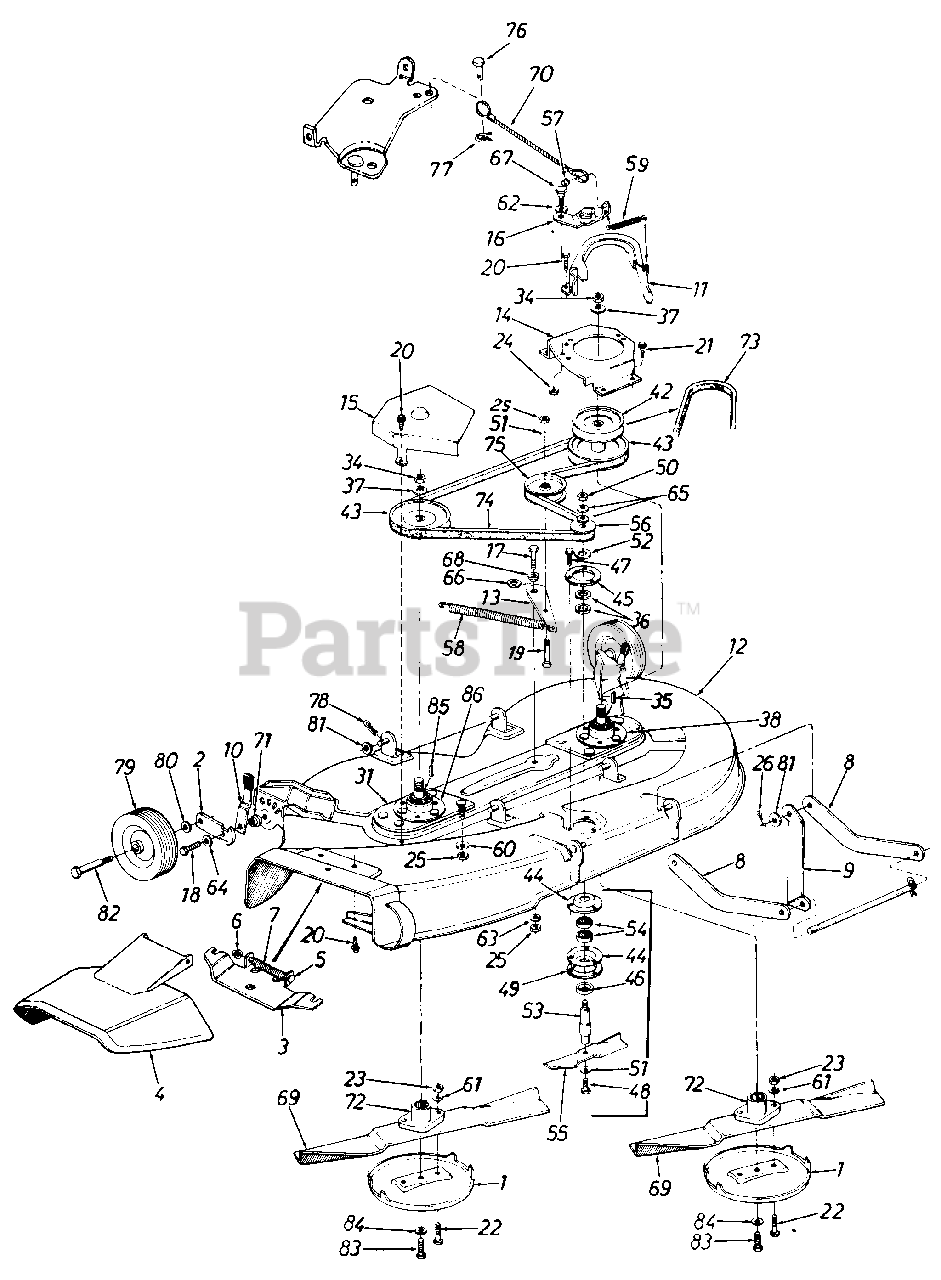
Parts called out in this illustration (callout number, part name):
1	Anti-Scalp Plate
2	Wheel Pivot Bar
3	Adapter
4	Chute Cover Ass'y.
5	Hinge Pin
6	Cap Speed Nut 1/4" Rod.
7	Torsion Spring
11	Belt Guard
12	44" Deck Ass'y.
13	Idler Bracket
14	Pulley Cover-L.H.
17	Hex Bolt 3/8-24 x 1.00"
18	Hex Bolt 3/8-24 x 1.25"Lg
19	Hex Bolt 3/8-24 x 1.50"
20	Hex Wash. S-Tapp Scr.1/4-20 x .50"
21	Hex Wash. Hd. Tapp Scr. 5/16-18 x .75" Lg.
22	Hex Bolt 5/16-24 x 1.25" (Grade 5)
23	Hex Nut 5/16-24 Thd.
24	Hex Cent. L.-Nut 5/16-18 Thd.
25	Hex Nut 3/8-24 Thd.
26	Cotter Pin 3/32 Dia. x 1.00" Lg.
34	Hex Jam Nut 5/8-18 Thd.
35	Square Key 3/16 x 2.25" Lg.
36	Fl. Wash. 5/8" I.D. x 15/16" O.D.
37	Bell. Wash. .630 I.D. x 1.25 x .090
38	L.H. Blade Spindle Ass'y. Comp.
42	5/8 "V"Pulley .79 I.D. x 5.75 O.D.
43	"V"Pulley .79 I.D. x 6.50 O.D.
44	1-3/8" I.D. Bearing Housing
45	Reinforcement Plate
46	Bearing Shield
47	Hex "B" Tap Scr. .250" x 1.0" Lg.
48	Hex Cl.-Scr. 3/8-24 x .88 Lg.
49	Reinforcement Plate
50	Hex Jam Nut 1/2-20 Thd.
51	Bell.-Wash. .400 I.D. x .88 O.D. x .060
52	Fl.-Wash. .635 x 1.04 O.D. x .1 20"
53	6.5" Blade Spindle
54	Ball Brg. .62 I.D. x 1.30" O.D. x .44"
55	6.50" Blade
56	1/2" V-Pulley Half .625 I.D. x 2.25" O.D.
57	Cap Speed Nut 1/4" Rod.
58	Extension Spring .73 O.D. x 4.31 Lg.
59	Extension Spring
60	Bell.-Wash. .400 I.D. x .88 O.D. x .060
61	L.-Wash. 5/16" I.D.
62	Spring Wash. .445 I.D. x .75 O.D. x .017
64	Bell.-Wash. .400 I.D. x 1.13 O.D. x .030
65	Bell.-Wash. .505 I.D. x 1.00 O.D. x .075
66	Spring Wash. .650 I.D. x .875 O.D. x .015 Thk.
67	Shld. Bolt .437 Dia. x .180
68	Shld. Spacer.625 I.D.
69	Mower Blade 21.88
70	Brake Cable Ass'y.
71	Shld. Spacer
72	Blade Adapter
73	"V"Belt 1/2 x 56" 4.
74	"V"Belt 1/2 x 74" 4.
75	Fl.-Idler w/Flanges 3.50 O.D.
76	Clevis Pin 1/4 Dia. x .53 Lg.
77	Intern. Cotter Pin 5/16" Dia.
78	Intern. Cotter Pin 1/2" Dia.
79	Deck Wheel 6.0 x 1.38
80	Bell.-Wash. .400 I.D. x .88 O.D. x .060
81	Fl.-Wash. .531 I.D. x .93 O.D. x .090
82	Shoulder Bolt 3/8-16 x 1.41
83	Hex Bolt 3/8-24 x .88" 4.
84	L.-Washer 3/8 I.D.
85	Sq. Key 3/16 x .75" 4.
86	R.H. Blade Spindle Ass'y. Comp.
